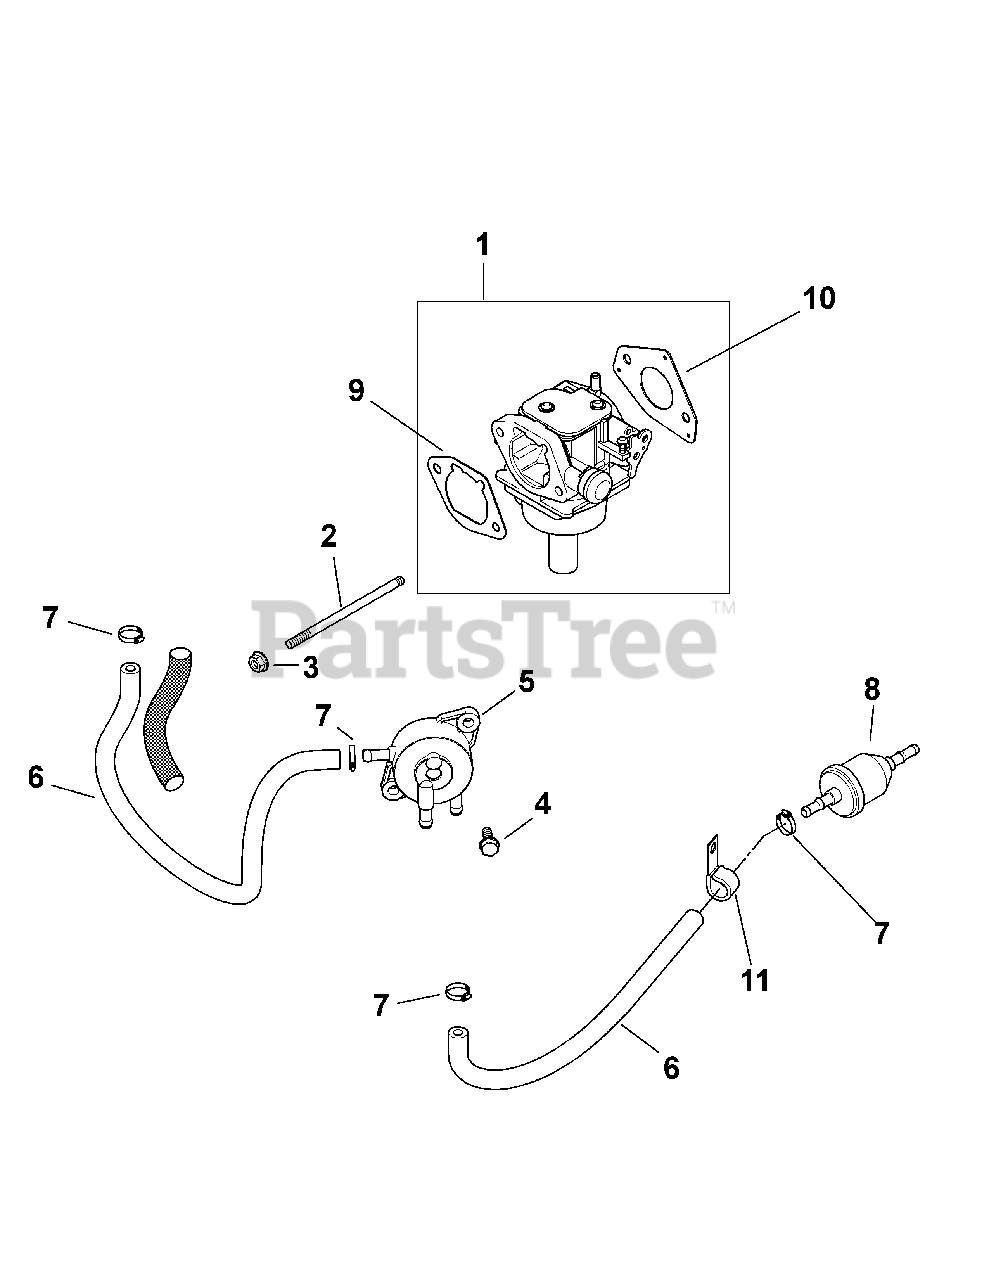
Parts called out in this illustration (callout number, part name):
1	Carburetor Kit
2	Stud, M6 x 1.0 x 106
3	Flange Nut, M6 x 1.0
4	Tap Screw, M6 x 1.7 x 18
6	Fuel Line
7	Hose Clamp, 1/2
9	Air Cleaner Base Gasket
10	Carburetor Gasket
